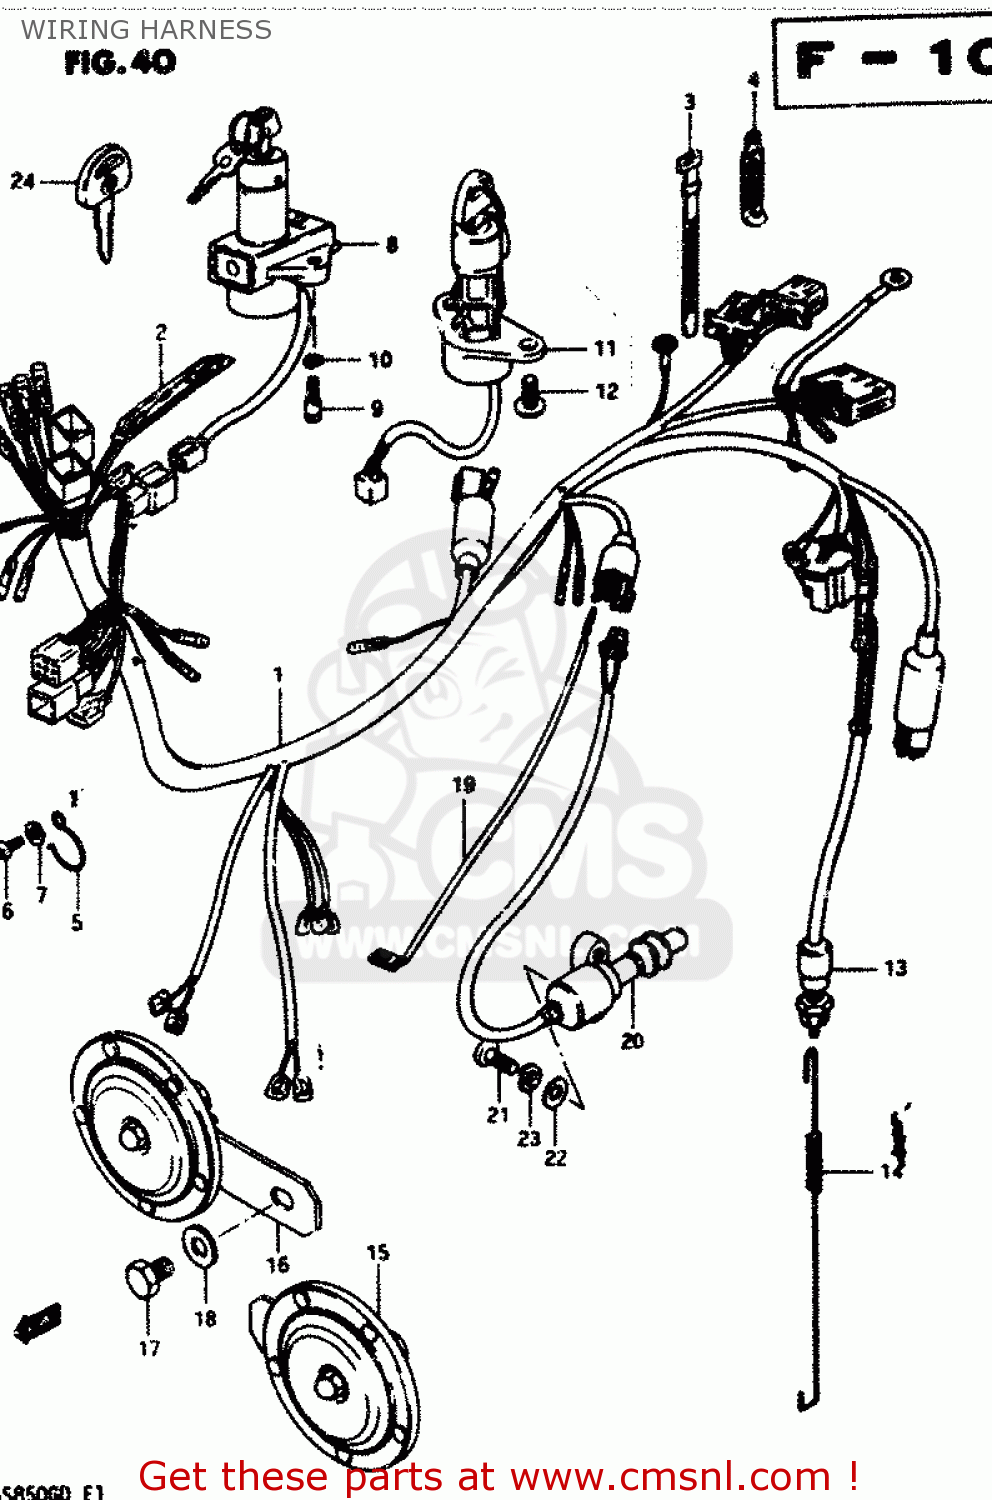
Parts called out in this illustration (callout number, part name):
1	HARNESS,WIRING
2	DIODE
3	CLAMP(L:120)
4	CLAMP
5	GUIDE,WIRING HARNESS
6	SCREW 6X12
7	WASHER
8	SWITCH ASSY,IGNITION
9	BOLT
10	LOCK WASHER
11	SWITCH ASSEMBLY,IGNITION
12	SCREW 6X12
13	SWITCH ASSEMBLY,STOP LAMP
14	SPRING
15	HORN ASSEMBLY,LOW PITCH
16	HORN ASSEMBLY,HIGH PITCH
17	BOLT 8X12
18	WASHER
19	WIRE
20	SWITCH ASSEMBLY,SIDE STAND
21	BOLT
22	WASHER
23	LOCK WASHER
24	KEY,BLANK
